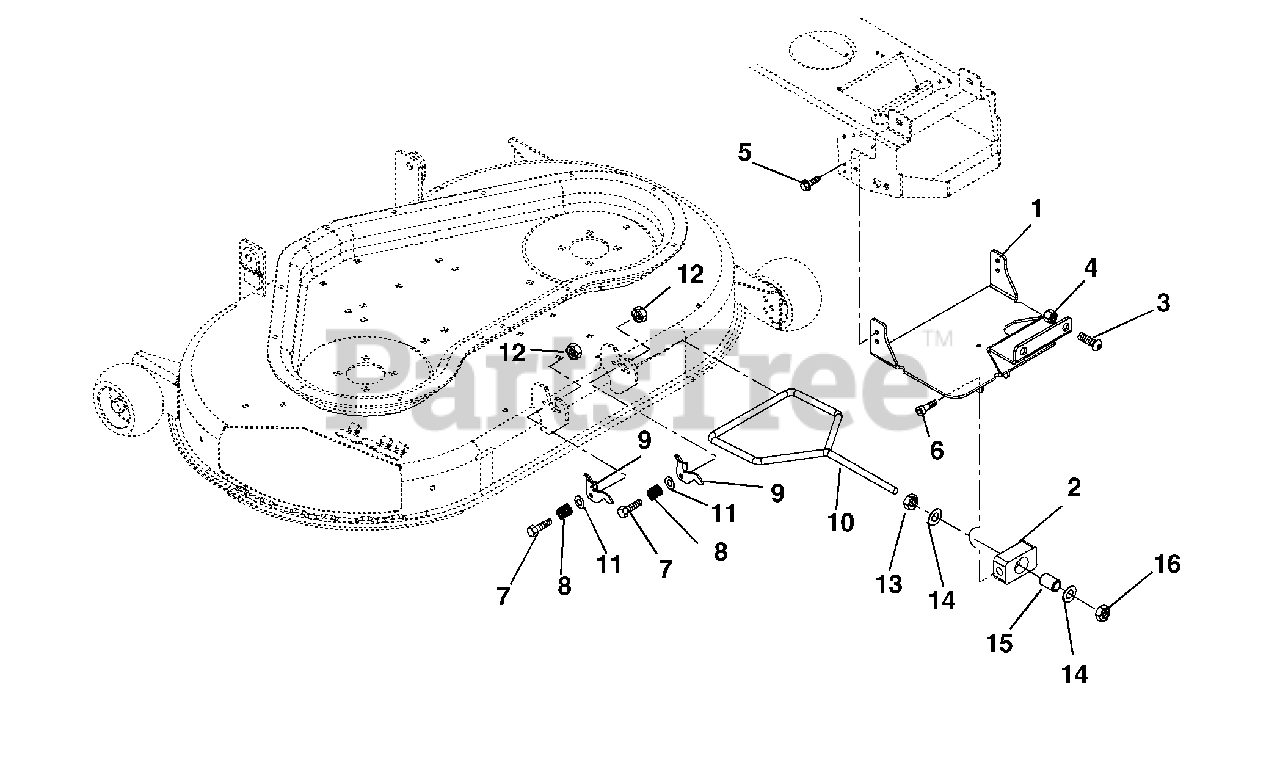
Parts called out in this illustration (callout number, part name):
1	BRACKET, FRONT MOUNT (WLDMNT)
2	MOUNT, 42" DECK FRONT
3	BOLT,.5-13 X 1.0 BUTTON HEAD
4	@NUT-LK-CTR .50-13 YWZC
5	SCR-TAP .312-18X.50 HWH PL TR
6	SCR-SKH .375X16X.50
7	@BLT-HEX .25-20X1.25 GR5 YWZC
8	SG-COMP .058X.68X.75
9	RETAINER, BRACE
10	ROD, LINK
11	@WSHR-FL-STL.312X.734X.065 YWZ
12	@NUT-LK-NYL .250-20 YWZC
13	@NUT-LK-CTR .50-13 YWZC
14	@WSHR-FL-STL.531X1.06X.095YWZC
15	BSHG-SLV .500X.750X.780
16	@NUT-LK-NYL .50-13 YWZC
